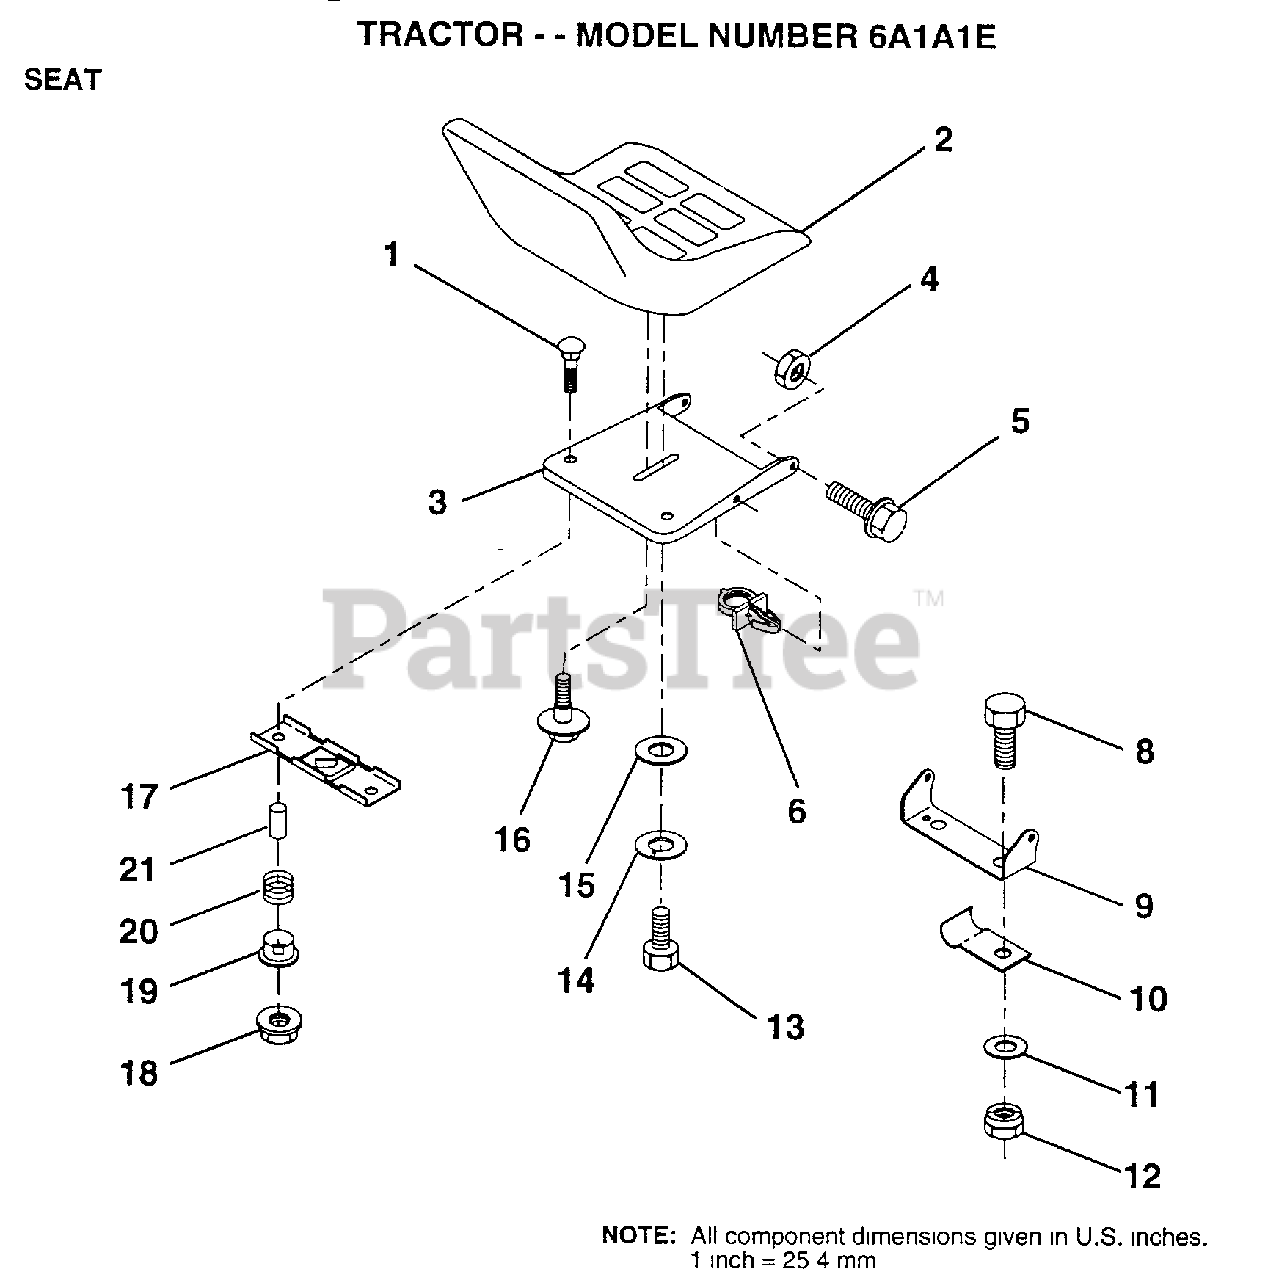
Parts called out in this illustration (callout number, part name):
4	NUT
5	"BOLT,SHOULDER"
6	CLIP.PUSH-IN.HING
7	BOLT
9	BRACKET PVT SEAT
10	"CLIP,INSULATOR"
11	WASHER
12	NUT
13	BOLT
14	LOCKWASHER
15	WASHER
16	"BOLT,SHOULDER"
17	BRKT SWITCH
19	BUSHING
20	SPRING
21	SPLIT SPACER
